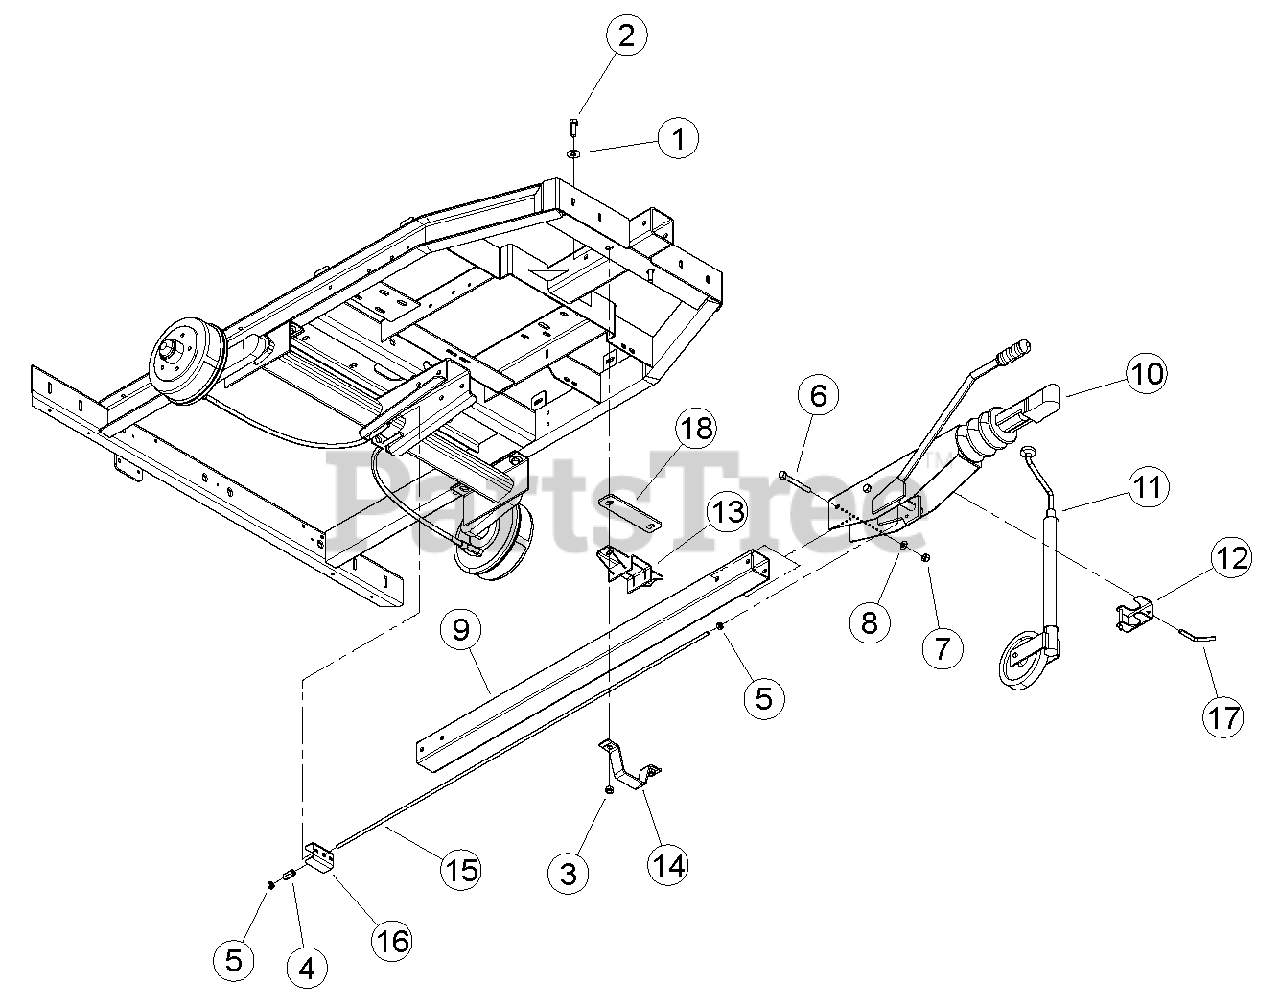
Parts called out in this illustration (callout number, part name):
1	WASHER, 1/2 FLAT ZP
2	BOLT, M12 X 1.75 X 40 HEX HD GR8.8
3	NUT, M12 X 1.75 HEX NYLOCK TYPE NEYZP
4	NUT, SPHERICAL M10 X 35MM
5	NUT, M10 HEX
6	BOLT, M12 X 100 CLASS 10.9
7	NUT, M12 HEX
8	WASHER, M12 FLAT
9	DRAWBAR, 70MM X 70MM
10	COUPLER, 50MM W/ BRAKE HANDLE
11	JACK, JOCKEY WHEEL
12	CLAMP, JOCKEY WHEEL
13	MOUNT, FRONT DRAWBAR
14	CLAMP, FRONT DRAWBAR
15	ROD, BRAKE CONTROL
16	BRACKET, BALANCE BAR
17	HANDLE, JOCKEY WHEEL CLAMP
18	PLA158TE, DRAWBAR MOUNT (WAS 77356-12, REMOVED)
